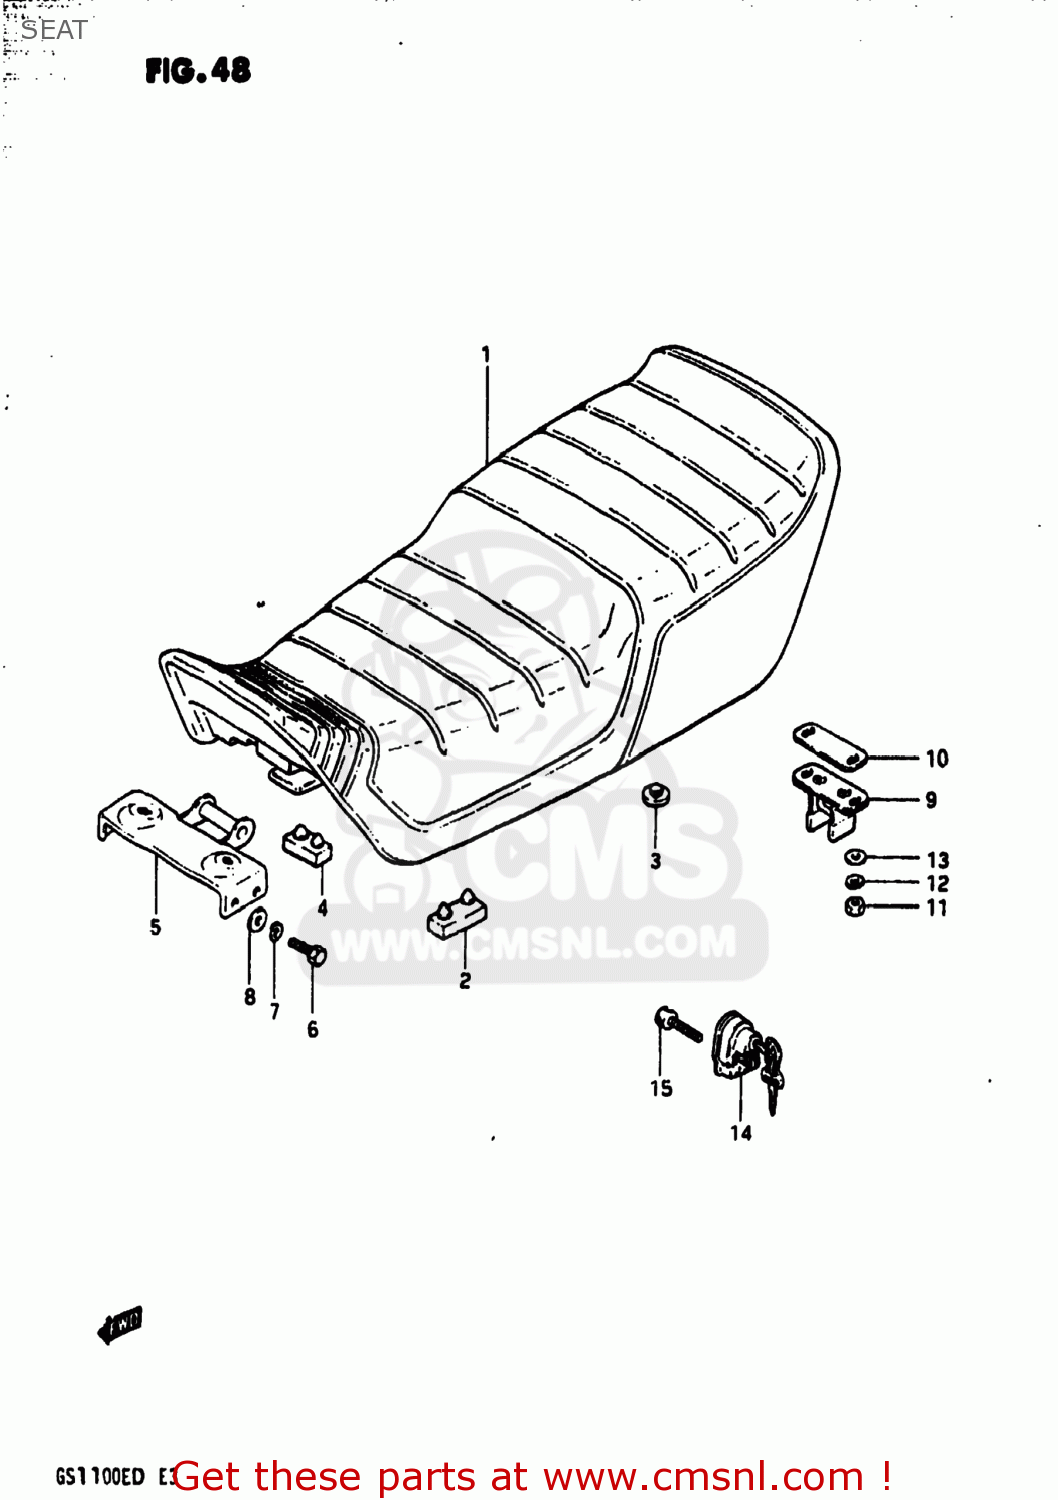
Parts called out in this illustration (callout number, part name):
1	SEAT ASSEMBLY
2	CUSHION
3	CUSHION
4	CUSHION
5	PLATE,SEAT HOOK
6	BOLT
7	LOCK WASHER
8	WASHER
9	STRIKER,SEAT LOCK
10	SHIM,SEAT LOCK STRIKER
11	NUT 6MM
12	LOCK WASHER
13	WASHER
14	LOCK ASSY,HELMET
15	BOLT 5X25
